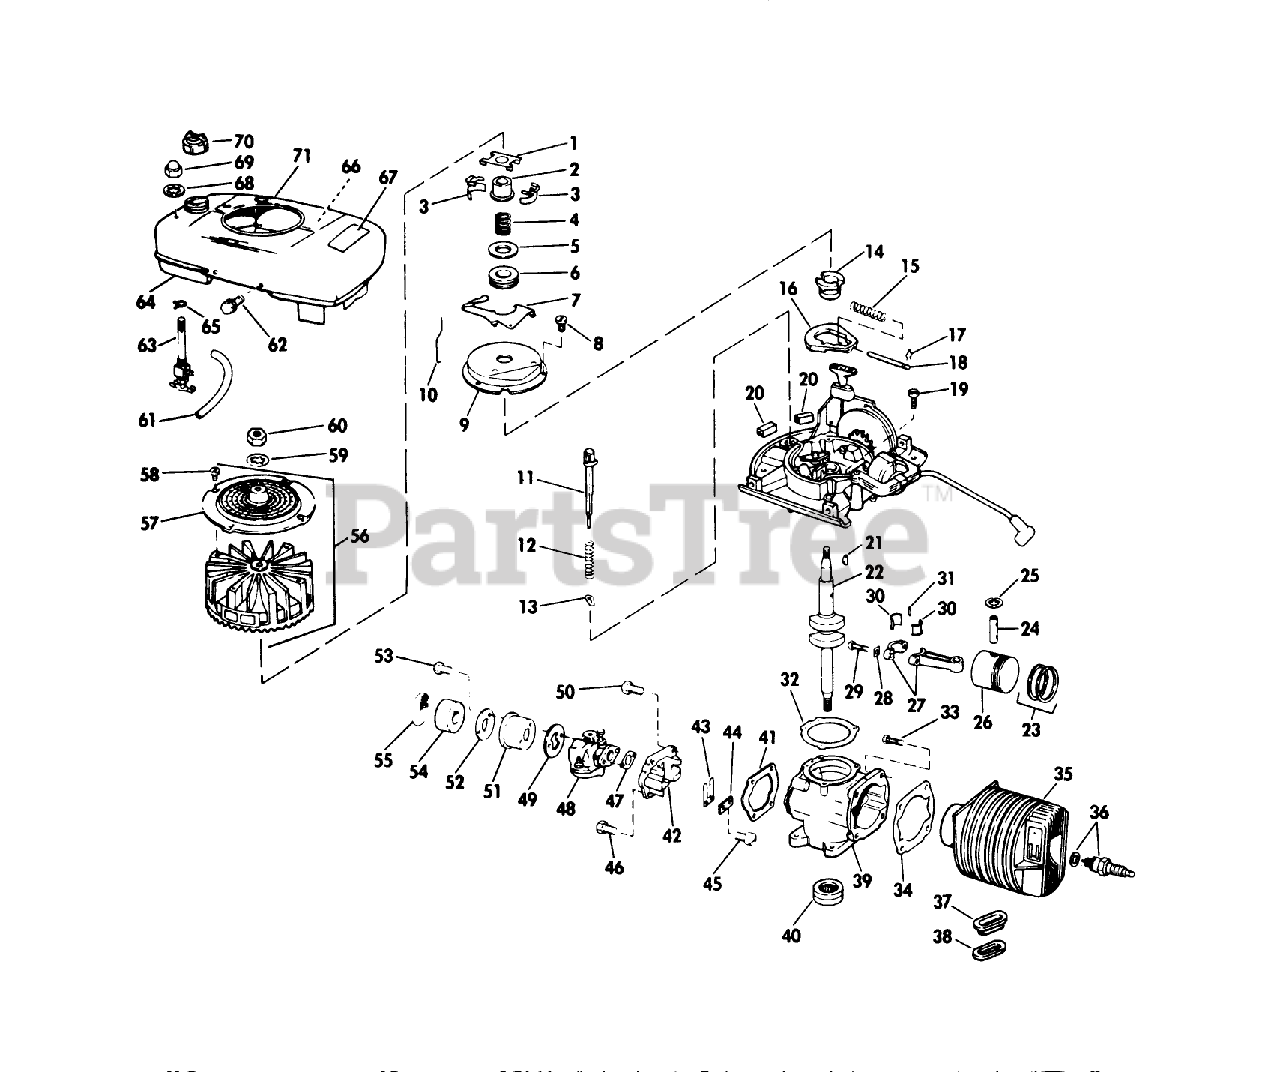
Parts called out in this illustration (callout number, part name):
2	COLLAR S
6	THRUST COLLAR S
7	LEVER-GOVERNOR S
8	SCREW S
9	DUST COVER S
12	SPRING S
14	SPARK ADV. S
15	SPARK ADV. SPRING S
16	FLYWEIGHT S
17	SPARK ADJ. SPRING
18	PIN,SPARK ADV. S
19	SCREW S
25	RING-RETAINING
30	LINER ASM
32	GASKET S
34	GASKET S
36	Spark Plug and Gasket
38	GASKET S
41	GASKET S
42	REED PLATE AY. S
44	PLATE-BACKUP, REED
46	SCREW S
47	GASKET S
49	GASKET S
50	SCREW S
52	BACK-UP PLATE
54	ELEMENT
56	Flywheel Screen Assy.
58	SCREW F
62	SCREW S
63	VALVE&SCREEN SM
65	CLAMP - HOSE S
69	PALNUT S
